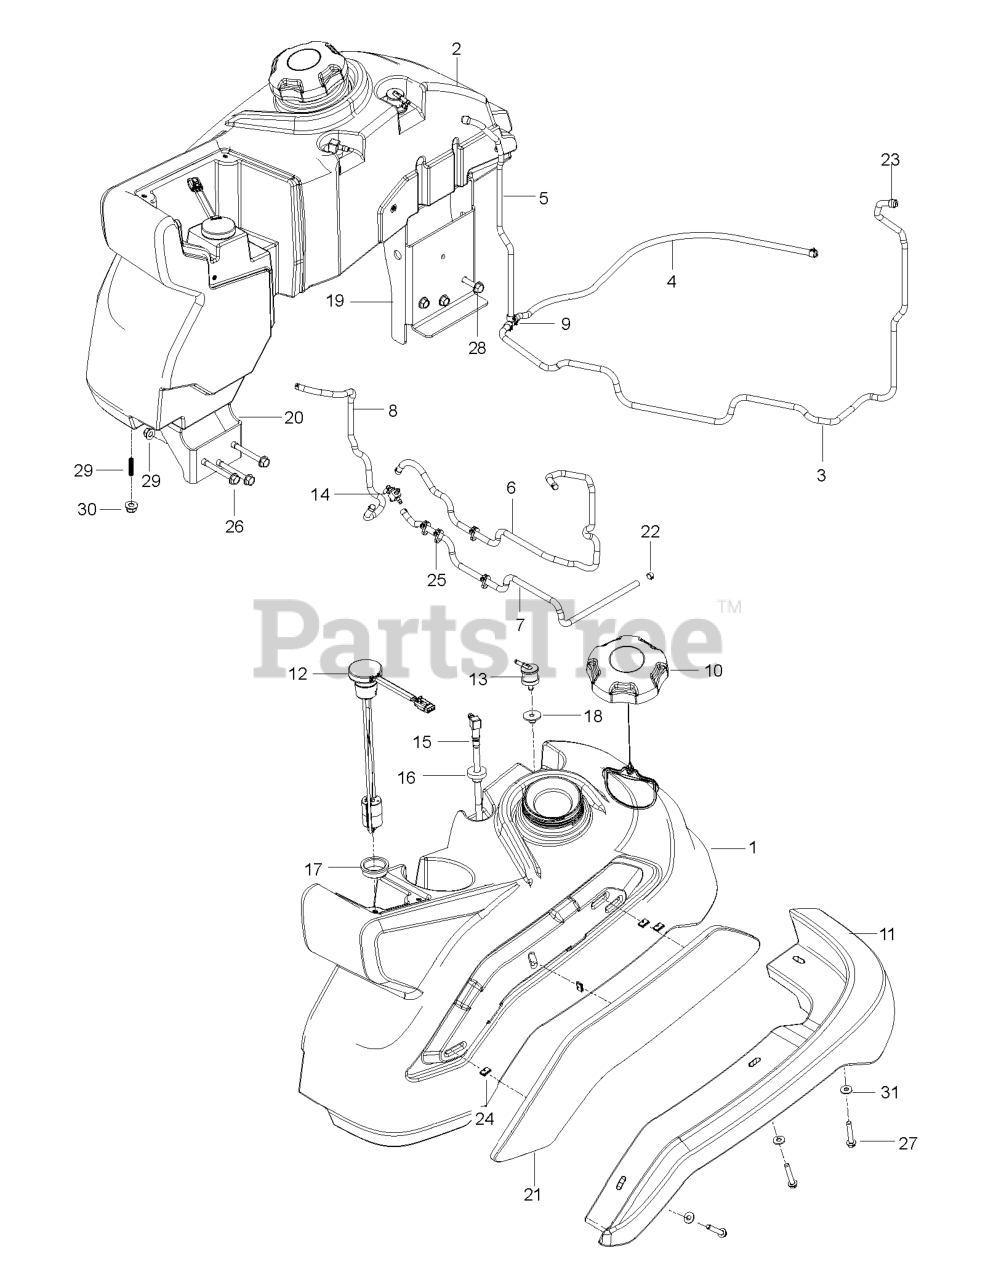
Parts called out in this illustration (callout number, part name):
1	FUEL.TANK.ASM.LH.PZ.REFRESH.18
2	FUEL.TANK.ASM.RH.PZ.REFRESH.18
3	HOSE.3/16".VAPOR.LINE.50"LGTH
4	HOSE 3/16" VAPOR LINE 11" LENG
5	HOSE.3/16".VAPOR.LINE.17"LGTH
6	HOSE 1/4" LOW PERMEATION FUEL
7	HOSE 1/4" LOW PERMEATION FUEL
8	HOSE.1/4".LOW.PERM.FUEL.LN.24"
9	TEE, FUEL LINE 3/16"
10	CAP, FUEL
11	GUARD.MUD.RH
11	GUARD.MUD.LH
12	SENSOR.FUEL.LVL.FLOAT.V500
13	VALVE.FUEL.CHECK
14	FUEL VALVE
15	TUBE.ASM.FUEL.TANK.PICK-UP.LH
15	TUBE.ASM.FUEL.TANK.PICK-UP.RH
16	BUSHING OUTLET T
17	GROMMET, FUEL SENSOR
18	GROMMET.CHECK.FUEL
19	BRACKET.FUEL.TANK.REAR.SUP.431
20	BRACKET.FUEL.TANK.REAR.SUP.431
21	COVER.LH.FUEL.TANK/CONSOLE APP
21	COVER.RH.FUEL.TANK/CONSOLE APP
22	HOSE CLAMP
23	CLAMP, HOSE
24	CLIP.U-TYPE
25	TIE WRAP, 8-3/8", W/CLIP
26	BOLT HEX FLGHD 5/16-18X3 GR. 5
27	SCREW.1/4-20X1.5IN.HEX.MACH
28	SCREW
29	SCREW.5/16-18X1.25"THREADED
30	5/16-18 NYLOC FLANGE NUT
31	WASHER
